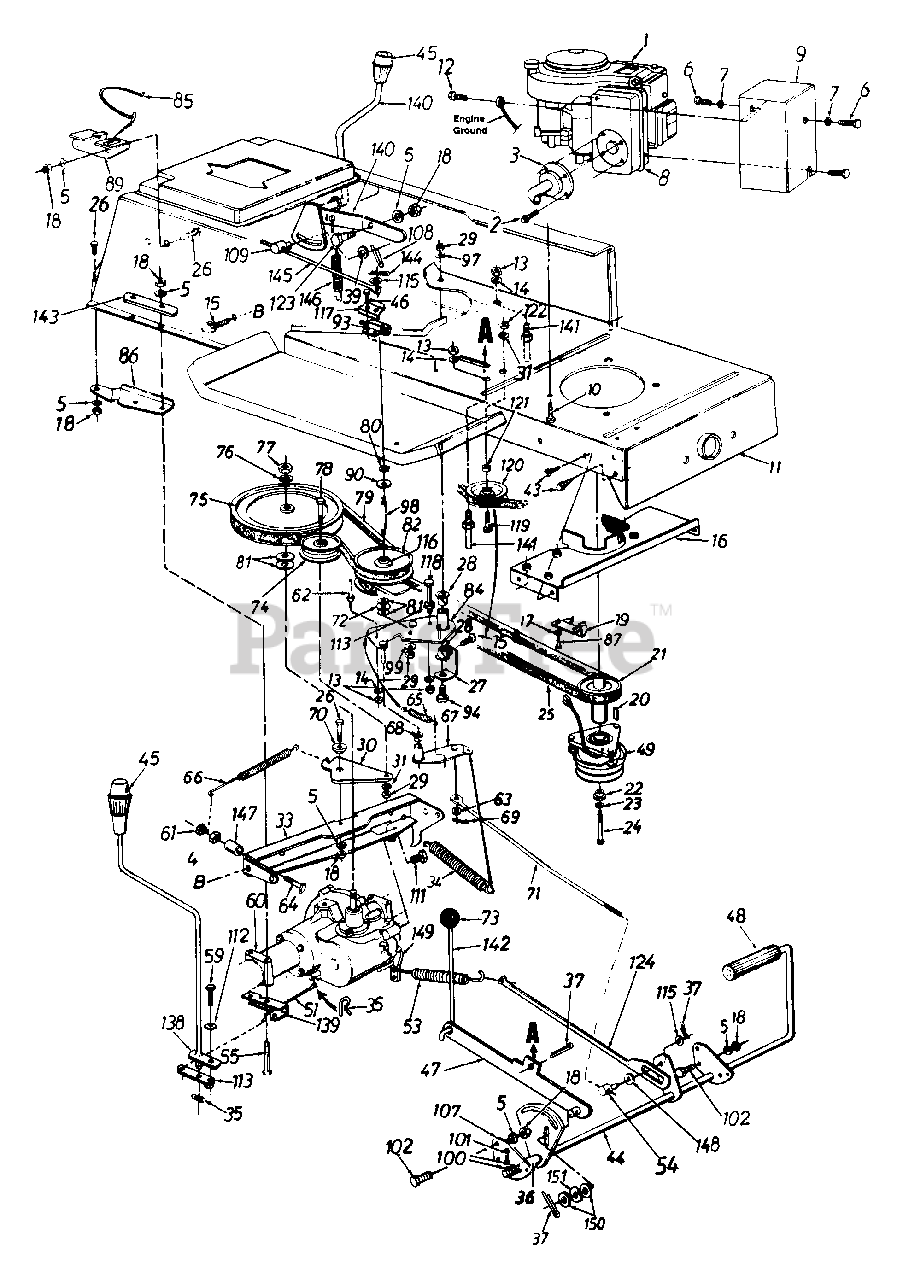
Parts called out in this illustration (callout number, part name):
1	Engine
2	Hex Wash. Hd. F-Tap Scr. #8-32 x .38" Lg.
3	Exhaust Pipe Ass'y.
4	Hex Nut 5/16-24 Thd.
5	L-Wash. 5/16" I.D.
6	Hex Cap Scr. M6-1 x 14 MM Lg.
7	Bell-Wash. .265" I.D. x .75" O.D.
8	Muffler - Supplied by Engine Manufacturer
9	Muffler Heat Shield Ass'y.
10	Hex Wash. Hd. TT-Tap Scr, 3/8-16 x 1" Lg.
11	Lower Frame Ass'y.
12	Hex Bolt M6-1" x 10 MM Lg. (Gr. 5)
13	Hex Nut 1/4-20 Thd.
14	L-Wash. 1/4" I.D.
15	Hex Wash. TT-Tap Scr. 5/16-18 x .62" Lg.
16	Belt Guard Brkt. Ass'y.
17	Bell-Wash. .345" I.D. x .88"
18	Hex Nut 5/16-18 Thd.
21	Engine Pulley
22	Shld. Spacer .445" I.D.
23	L-Wash. 7/16" I.D.
24	Hex Bolt 7/16-20 x 3.25" Lg.
25	Variable-Speed Belt
26	Hex Bolt 5/16-18 x .75" Lg.
27	Bearing Shaft Bracket Ass'y.
28	Flanged Nyliner Brg. .63" I.D. x .6" Lg.
29	Hex Nut 3/8-24 Thd.
30	Idler Bracket
31	L-Wash. 3/8" I.D.
33	Transaxle Support Brkt.
34	Ext. Spring .94" O.D. x 7.58"
35	Inter. Cotter Pin
36	Spacer .63" I.D.
37	Cotter Pin 1/8" Dia. x 1.0" Lg.
39	FL-Wash. .51" I.D. x .75"
43	Hex Wash. Hd. S-Tap Scr. 1/4-20 x .50" Lg.
44	Clutch/Brake Pedal Ass'y.
46	Truss Mach. B-Tap Scr. #10 x .5" Lg.
47	Parking Brake Lockout Brkt. Ass'y.
48	Foot Pad
49	Electric Clutch
51	Shift Lever Rod
53	Ext. Spring 3.6"
54	Ferrule
55	Hex Bolt 5/16-18 x 3.25"
59	Hex Bolt 1/4-28 x .62" Lg.
60	Transaxle Complete
61	Hex L-Nut 1/4-20 Thd.
62	Belt Guard Pin 1/4-20 Thd.
63	Fl-Wash. .34" I.D. x .68" O.D.
64	Hex Wash. TT-Tap Scr. 1/4-20 x 1.75"
65	Ext. Spring 2.59" Lg.
66	Ext. Spring .5" O.D. x 4.35"
68	Flanged Bearing
69	Cotter Pin 3/32" Dia.
70	Shoulder Spacer .27" Lg.
71	Speed Control Link
72	Truss Bearing .56 Dia. x 1.25"
74	Fl-Idler Pulley 3.25" x .75"
76	L-Wash. 1/2" I.D.
77	Hex Jam Nut 1/2-20 Thd.
78	Hex Bolt 3/8-24 x 1.75" Lg.
79	Variable Speed Belt
80	Snap Ring .56" Dia.
81	Fl-Wash. .56" I.D. x 1.0" O.D.
82	Variable Speed Pulley Ass'y. 5" O.D.
89	Speed Cont. Rod Brkt.
90	Teflon Washer .565" I.D.
93	Safety Switch (Clutch)
94	Shld. Bolt 3/8-24 x 3.12" Lg.
97	Bell-Wash. .38" I.D. x .88"
99	Bell-Wash. .39" I.D. x 1.12"
100	Fl-Wash. .64" I.D. x .94"
101	Cotter Pin 1/8" Dia. x 1.25" Lg.
102	Hex Wash. Hd. Scr. 5/16-18 x .62" Lg.
109	Ferrule
111	Hex Wash. Tap Scr.
112	Bell-Wash. .265" I.D. x .75"
113	Shift Lever Link Ass'y.
115	Fl-Wash. .385" I.D. x .62"
116	Needle Brgs.
117	Switch Plate
118	Hex Bolt 1/4-20 x 3.5" Lg.
119	Hex Bolt 3/8-16 x 1.25" Lg.
120	Fl-Idler w/Flanges 2.75" O.D.
121	Fl-Wash. .39" I.D. x 1.12" O.D.
122	Hex Nut 3/8-16 Thd.
123	Shld. Bolt .437" Dia. x .162"
124	Brake Rod Ass'y.
138	Shift Lever Ass'y.
139	Shift Lever Support Brkt.
140	Speed Selector Lever Ass'y.
141	Belt Guard Pin
142	Brake Lockout Rod
144	Cotter Pin 1/8" x 3/4" Lg.
145	Speed Selector Rod
146	Ext. Spring 3.97" Lg.
147	Spacer .326" I.D. x .47"
148	Fl-Wash. 5/8" I.D. x 1.25"
149	Actuating Arm
150	Fl-Wash. .385" I.D. x .87" O.D.
151	Wave Wash. .38" I.D. x .75"
